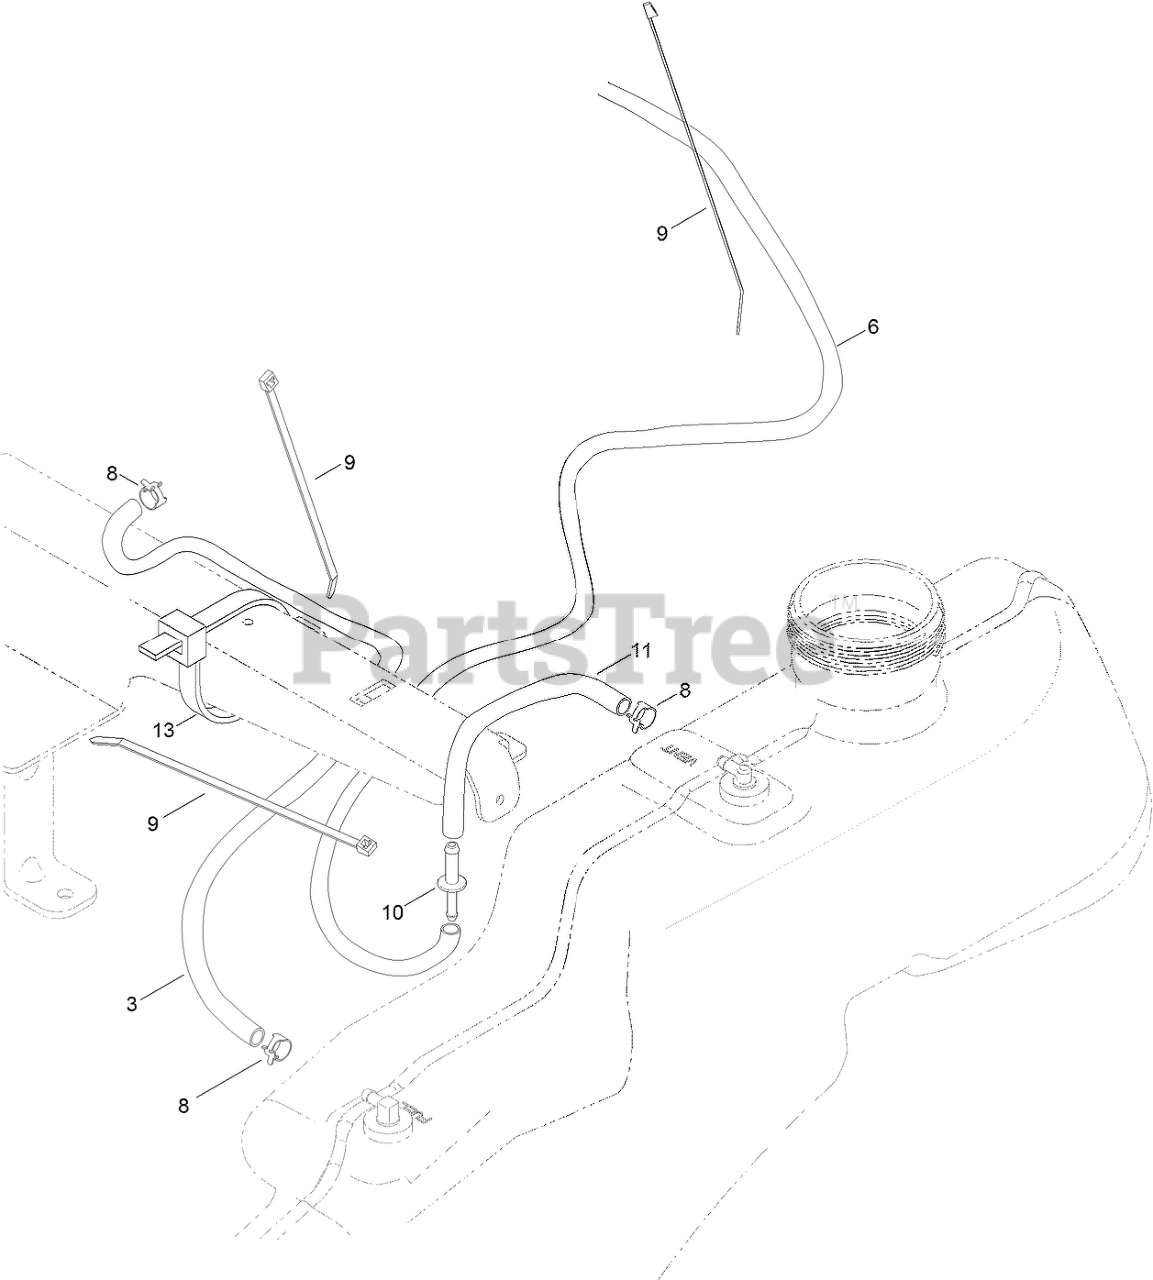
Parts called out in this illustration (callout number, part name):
3	HOSE-FUEL
6	HOSE-FUEL
8	CLAMP-HOSE
9	TIE-CABLE
10	ADAPTOR-ORIFICE
11	HOSE-FUEL
13	TIE-CABLE
